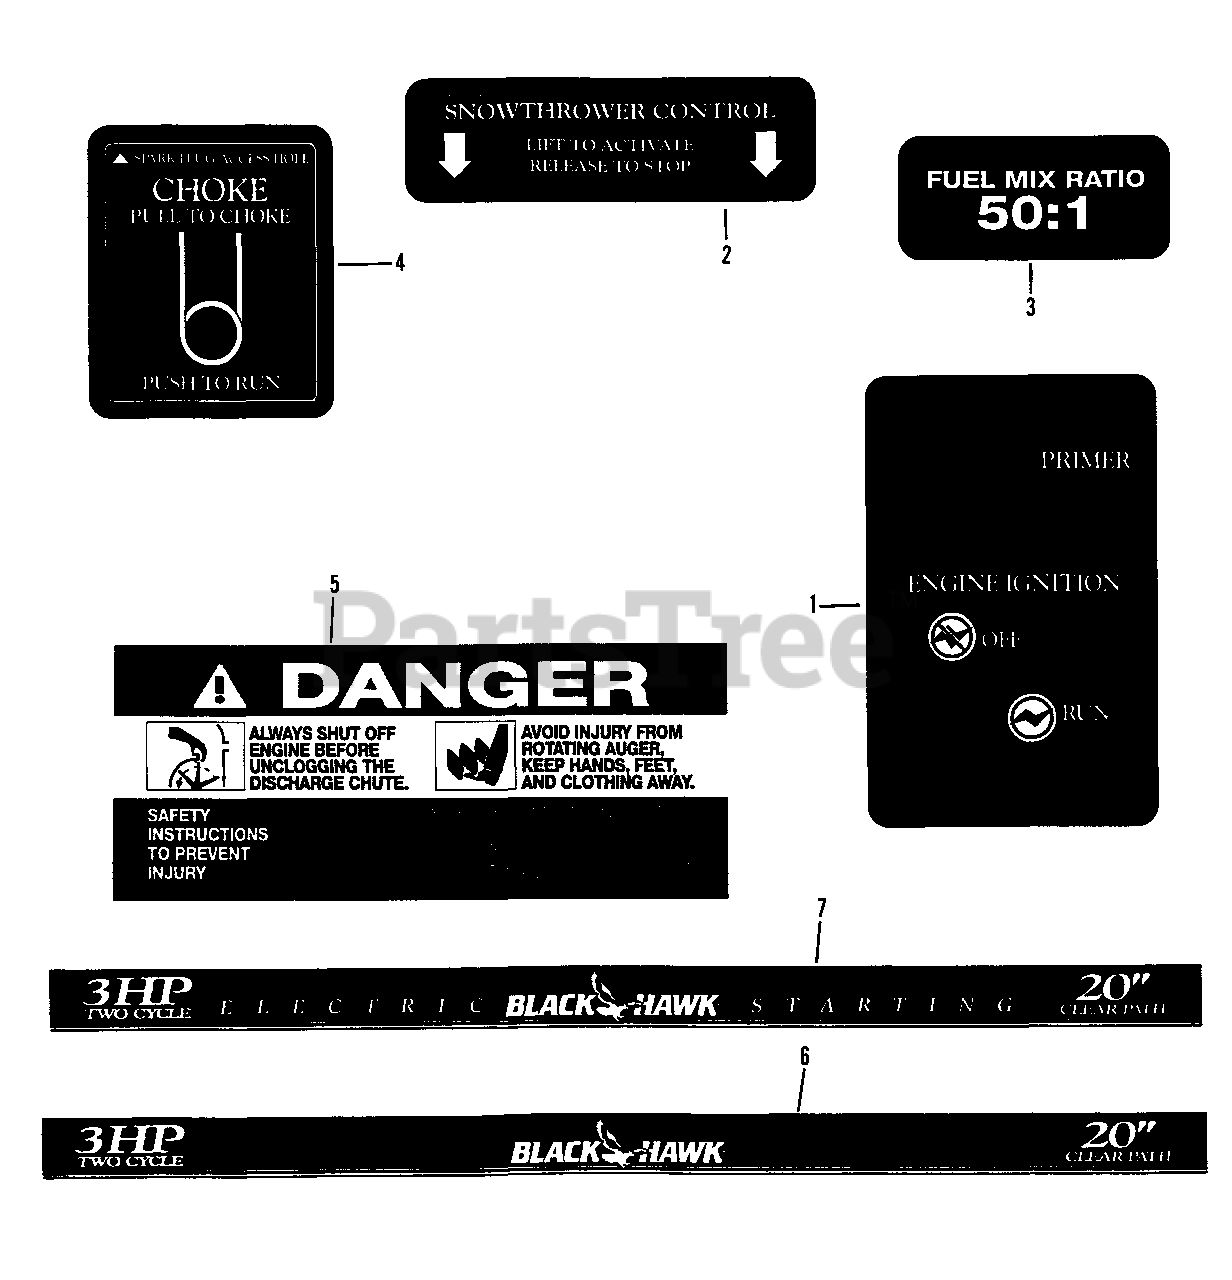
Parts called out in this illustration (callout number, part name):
1	DECAL, Ignition
2	DECAL, Auger Control
3	DECAL, Fuel Mix
4	DECAL, Choke
5	DECAL, Danger
6	DECAL, BLACKHAWK
7	DECAL, BLACKHAWK (Electric Start)
